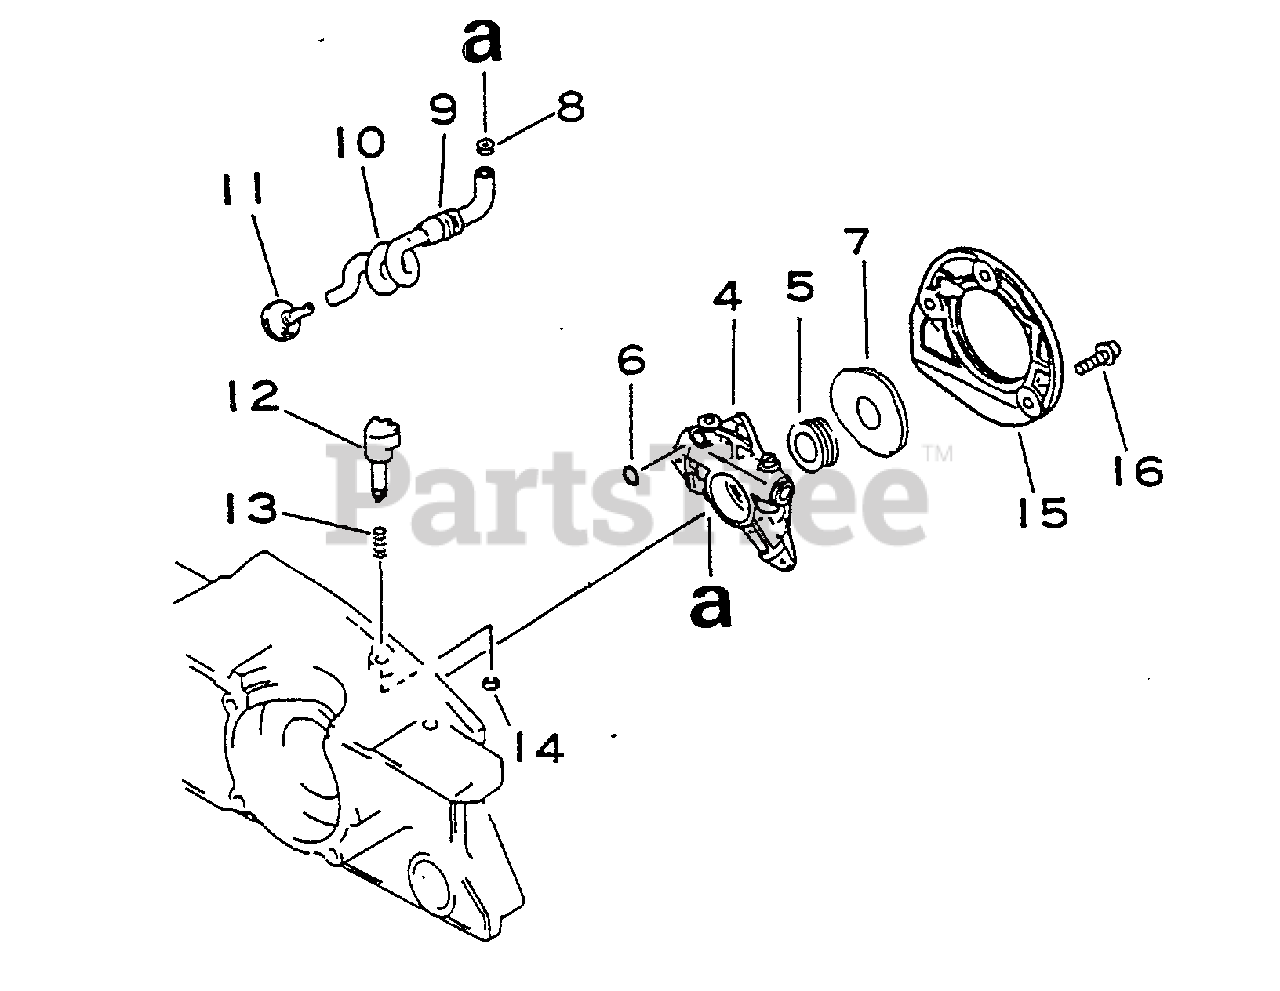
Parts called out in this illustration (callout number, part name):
4	AUTO-OILER ASSY
5	GEAR, WORM
6	O-RING 3
7	COVER
8	CLIP Ø6.5 MM
10	PIPE, OIL
11	FILTER, OIL
14	E-RING 3
15	COVER, OIL PUMP - ORANGE
16	SCREW 4×14
